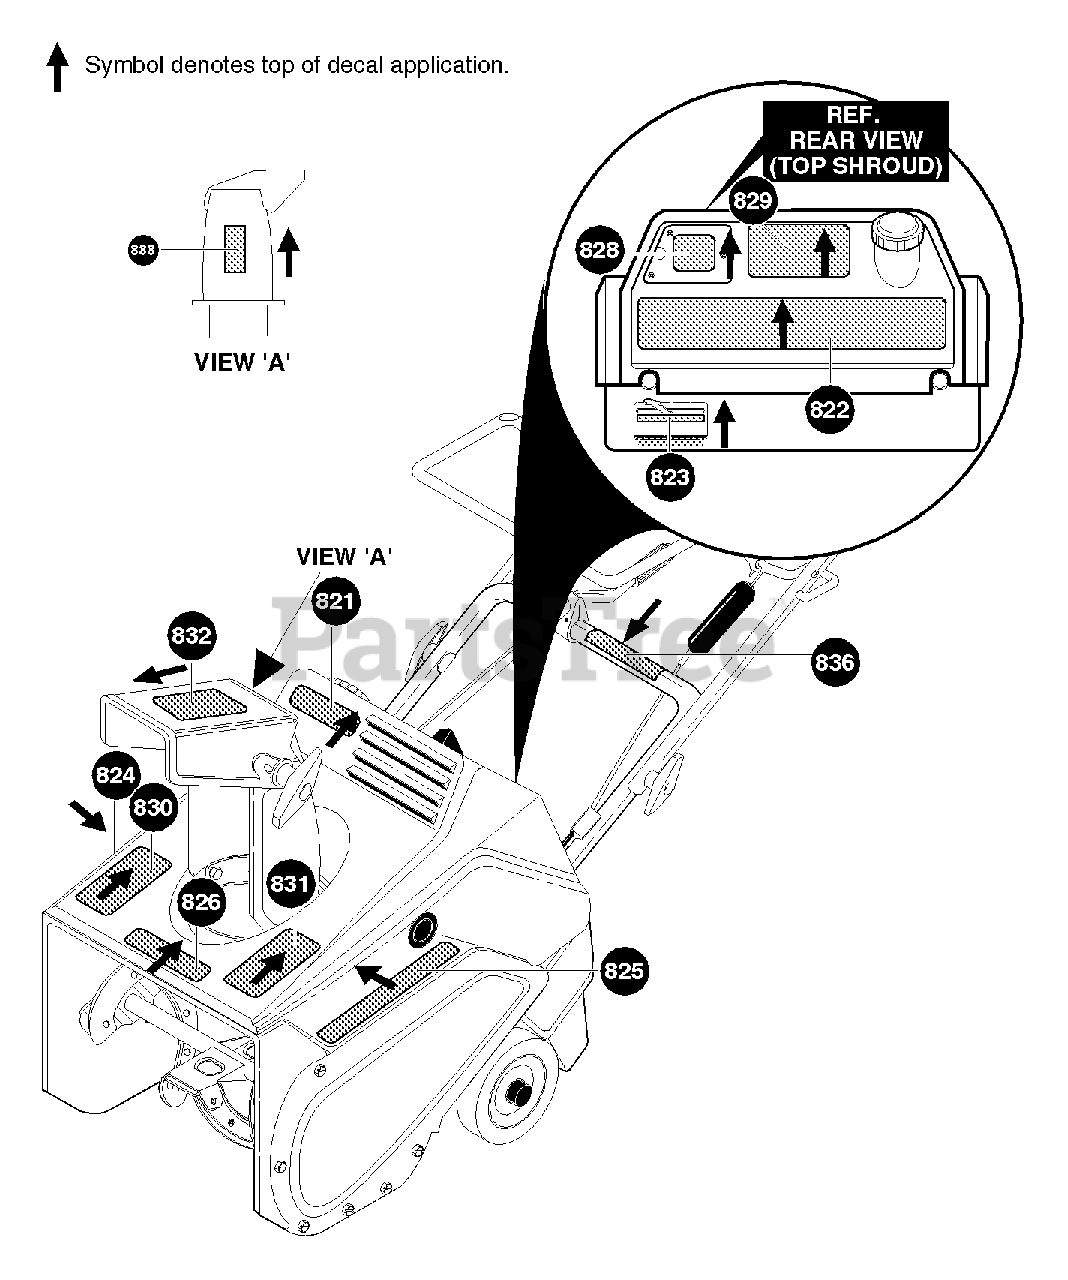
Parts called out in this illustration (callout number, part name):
821	DECAL, HUSQVARNA
822	DECAL, CONTROL PANEL
823	DECAL, OFF-CHOKE-ON
824	DECAL, SIDE PANEL. ST521 RH
825	DECAL, SIDE PANEL ST521 LH
826	DECAL, HUSQVARNA TOP COVER
828	DECAL, FUEL MIX ENG/FR
829	DECAL, START INSTRU ENG/FR
830	DECAL, DANGER CHUTE ENG/FR
831	DECAL, DANGER AUGER ENG/FR
832	DECAL, HUSQ "CROWN"
833	DECAL, SAFETY INSTRU ENG/FR
836	DECAL, AUGER CONTROL BAR
